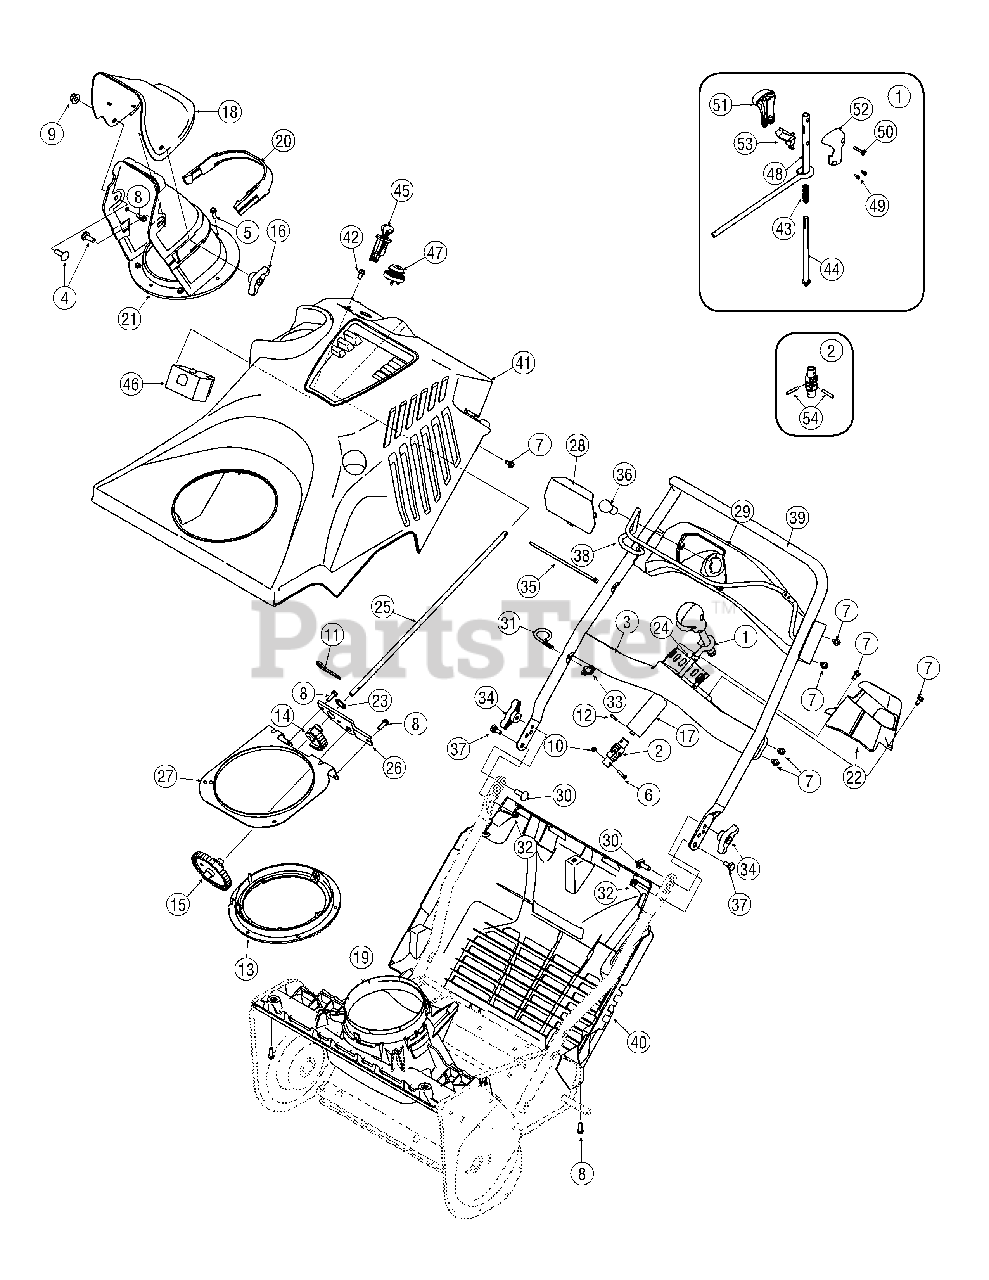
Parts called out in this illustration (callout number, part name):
1	Chute Rotation Control Assembly
2	Joint Block Assembly
3	Indicator Bracket Assembly
4	Carriage Bolt, 5/16-18 x .750
5	Hex Washer Screw, 1/4 x .750
6	Machine Screw, #8-32 x .88
7	Hex Washer Screw, 1/4-20 x 0.500
8	Hex Washer Screw, 1/4-15 x 0.750
9	Hex Lock Nut, #8-32
10	Hex Lock Nut, #8-32
11	Cotter Pin, .125 x 2.5
12	Spring Pin, .156 x .85
13	Bevel Gear, 95T
14	Spur Gear, 35T
15	Spur Gear, 40T/11T
16	Wing Knob, 5/16-18
17	Grip, 1.18 x 3.33
18	Upper Chute
19	Chute Adapter
20	Chute Plug
21	Lower Chute
22	Chute Rotation Cover
23	Flat Washer, .75 x 1.00 x .06
24	Plastic Bushing, .380
25	Chute Rotation Rod, 3/8
26	Gear Mounting Plate
27	Gear Retainer Bracket
28	Handle Panel Lens
29	Handle Panel
29	Light Label
30	Carriage Screw, 5/16-18 x 1.00
31	Eye Bolt, 1/4-20
32	Flange Lock Nut, 1/4-20
33	Wing Knob, 1/4-20
34	Wing Knob, 5/16-18
35	Cable Tie, 3/16 x .05 x 7.4
36	Lamp, #1141
37	Shoulder Screw, 1/4-20 x .375 x .148
38	Auger Control
39	Upper Handle
40	Bottom Cover Assembly
41	Cover Assembly
42	Hex Washer Screw, 1/4-15 x .50
43	Compression Spring, .460 x 1.469
44	Chute Rotation Rod
45	Ignition Switch Assembly
46	Electric Starter
48	Chute Rotation Rod Assembly
49	Screw, #6 x .375
50	Screw, #8 x 1.00
51	RH Control Knob
52	LH Control Knob
53	Joystick Trigger
54	Roll Pin, 3/16 x 1.1
